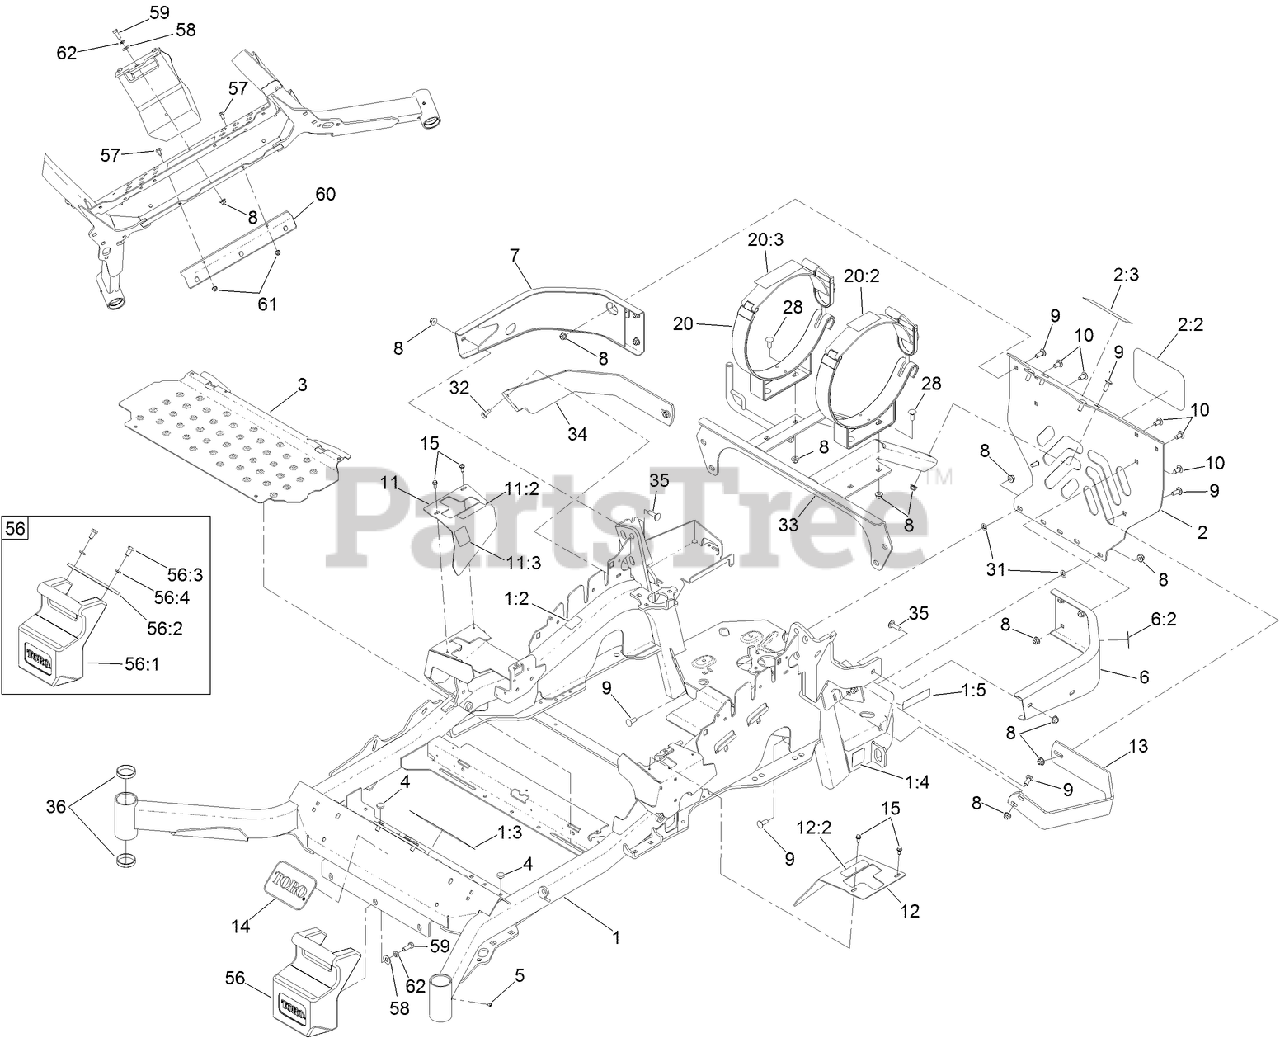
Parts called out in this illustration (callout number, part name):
1	MAINFRAME ASM
1:2	DECAL-WARNING
1:3	DECAL-DANGER
1:4	DECAL-HAZARD, PINCHED FINGER
1:5	DECAL-SPARK ARRESTER
2	LPG REAR GUARD ASM
2:2	DECAL
2:3	DECAL-LPG FUEL TANK REPLACEMENT
3	FLOORPAN
4	BUMPER
6	LH BUMPER ASM
6:2	DECAL-WARNING
7	BUMPER-RH
8	NUT-HF, NI
9	SCREW-CARR
10	SCREW-CARR
11	RH MOTION CONTROL COVER ASM
11:2	DECAL-CONTROL, MOTION
11:3	DECAL-PARK BRAKE, CE
12	LH MOTION CONTROL COVER ASM
12:2	DECAL-CONTROL, MOTION
13	GUARD-MUFFLER
14	DECAL
15	SCREW-HWH
20	TANK BRACKET ASM (SET)
20:2	DECAL-LPG WARNING
20:3	DECAL-LPG TANK SPEC
28	SCREW-HH
31	NUT-PUSH
32	SCREW-HWHTF
33	SUPPORT-TANK
34	STRAP-GUARD
35	BOLT-CARR
36	CUP-BEARING
56	WEIGHT ASM
56:1	WEIGHT-43 LB
56:2	TAB-SUPPORT, WEIGHT
56:3	SCREW-HH
56:4	SCREW-HH
57	SCREW-CARR
58	WASHER-FLAT
59	SCREW-HH
60	BRACKET-MOUNT, WEIGHT
61	NUT-HF, NI
62	SCREW-HH
